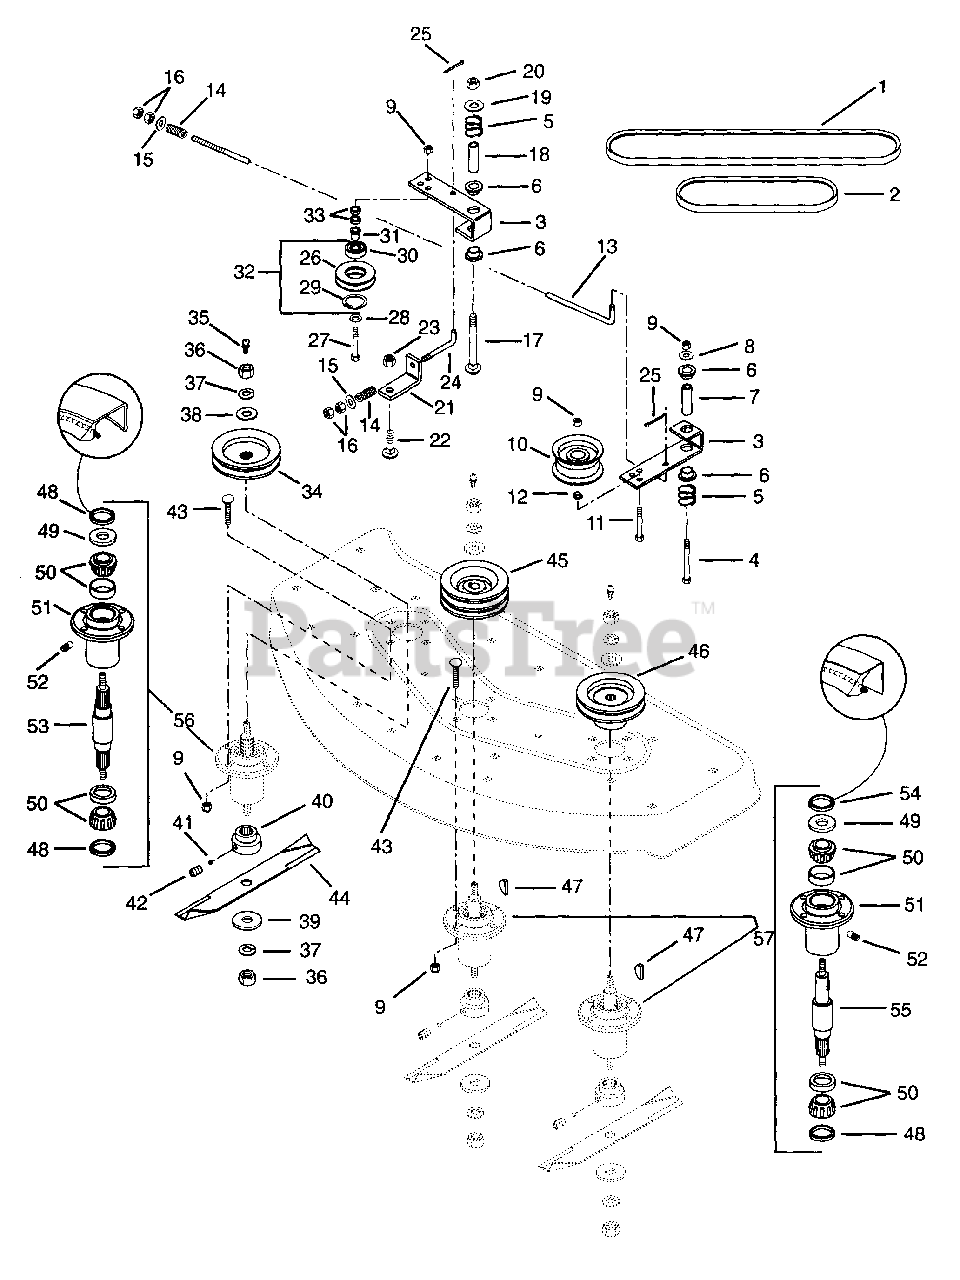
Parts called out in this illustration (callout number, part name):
1	V-Belt A-Section 48.00 x 513/.031
2	V-Belt A-Section 40.60 x .516/.031
3	Arm, Idler Pivot
4	Bolt-Hex .38-16 x 3.25 Grade 5
5	Spring-Compression .085 x .80 x 1.00
6	Bushing-Flange .762 x 1.0 x .580 x 1.48
7	Bushing, Steel .437 x .750 x 2.44
8	Washer-Flat-Steel .438 x 1.000 x .083
9	Nut-Locking-Nylon .375-16 Grade 2
10	Idler-Flat 4-.687 x .38
11	Bolt-Hex .38-16 x 2.25 Grade 5
12	Bushing-Flange .406 x .88 x .270 x .140
13	Rod, Idler 25.0
14	Spring-Compression .125 x .78 x 1.00
15	Washer-Flat-Steel .281 x .625 x .065
16	Nut-Hex .375-16 Grade 2
17	Bolt-Round Head Square Neck .50-16 x 3.50
18	Spacer .560 x .750 x 2.437
19	Washer-Flat-Steel .531 x 1.250 x .100
20	Nut-Locking .50-13 Hex
21	Bracket, Belt Tensioner
22	Bolt-Round Head Square Neck .31-18 x 1.0
23	Nut-Locking-Nylon .312-18 Grade 2
24	Rod, Idler
25	Pin-Cotter .09 x .75
26	Sheave, Idler
27	Bolt-Hex .38-16 x 2.00 Grade 5
28	Washer-Flat-Steel .375 x 1.125 x .065
29	Ring-Retaining-Internal 2.054 x .062
30	Bearing-Ball 1.85 x .78 x .55
31	Bushing-Flange .786 x 1.0 x .79
32	Assembly, Idler Sheave
33	Bushing .406 x .750 x .188
34	Sheave
35	Fitting-Lube 1/8
36	Nut-Hex .625-11 Grade 2
37	Washer-Locking .625 x .156
38	Washer-Flat-Steel .97 x 1.865 x .063
39	Washer
42	Screw-Set .25-20 x .25
43	Bolt, Round Head Square Neck .38-16 x 1.375
44	Blade
47	Key-Woodruff .25 x 1
48	Seal 1.987 x 1.375 x .313
49	Washer-Flat-Steel 1.007 x 1.542 x .062
50	Assembly, Bearing Cup & Cone
51	Housing, Bearing
52	Relief Fitting - Grease
53	Shaft, Spindle
54	Seal 1.987 x 1.500 x .313
55	Shaft, Spindle
56	Service Kit
57	Service Kit
